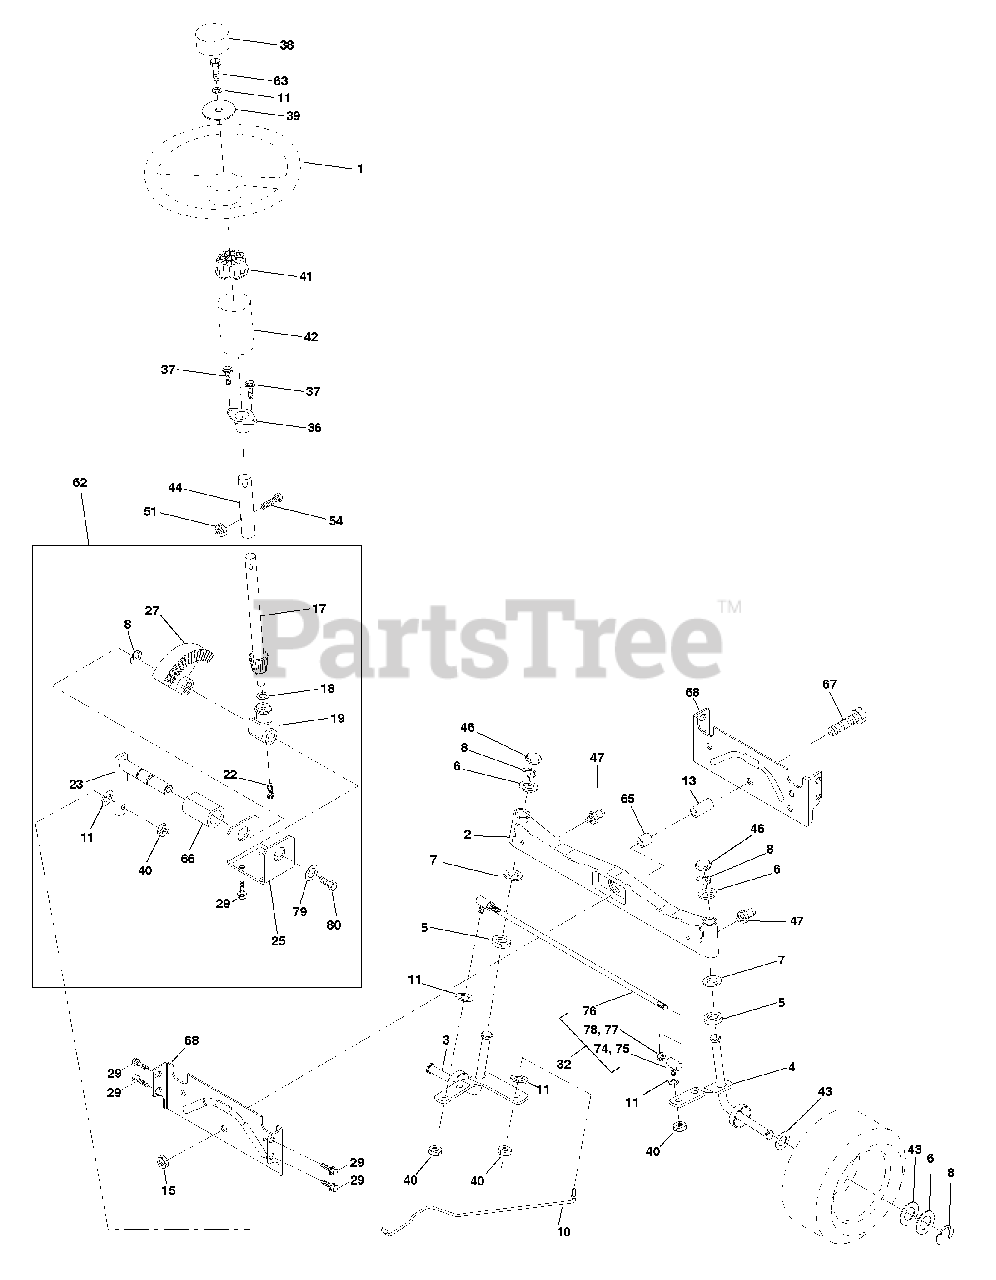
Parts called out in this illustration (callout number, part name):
1	Wheel Steering
2	Axle Front Casting Machined
3	Spindle Asm LH Cast 15"
4	Spindle Asm RH Cast 15"
5	Bearing Race Thrust Harden
6	Washer 25/32 X 1-5/8 X 16 Ga
7	Washer 27/32 X 1-1/4 X 16 Ga
8	Ring Klip #t5304-75
10	Link Drag Extended Cast
11	Washer Lock Hvy Hlcl Spr 3/8
13	Bearing Axle STLT/GT
15	Nut Lock Flange 5/8-11 Unc
17	Shaft Asm Strg
18	Washer Thrust 515x 750x 033
19	Support Shaft
22	Screw Hex Wshhd Torx
23	Shaft Asm Pittman
25	Bracket Steering
27	Gear Sector
29	Screw Thdrol 3/8-16x3/4 Ty-tt
32	Rod Asm Tie Ball J Adj VGT
36	Bushing Strg
38	Insert Cap Strg Wh Au
39	Washer 13/32 X 2-3/8 X 8 Ga
40	Lock nut
41	Adaptor Wheel Strg
42	Boot Steering Shaft
43	Washer 25/32 X 1 1/4 X 16 Ga
44	Extension Steering Shaft LR/LT
46	Cap Spindle Fr Top Blk
47	Fitting Grease
51	Nut Lock Hex w/Ins 5/16-18
54	Bolt Fin Hex 5/16-18 Unc x 1-1/4
62	Kit, Steering Assembly Svc
63	Bolt Fin Hex 3/8-16unc x 1 Gr. 5
65	Spacer Axle
66	Bearing Arm Pittman
67	Bolt, Fin Hex 5/8-11 UNC x 2-3/4
68	Axle, Brace
74	Joint Asm Ball Rh
75	Joint Asm Ball Lh
76	Rod Tie Ball J Adj
77	Nut Hex Jam 3/8-24 Unf Lh
78	Nut Hex Jam 3/8-24 Unf
79	Washer 13/32 x 1-1/4 x 12 Ga.
80	Bolt Hex Nylon 3/8-16 x 3/4
